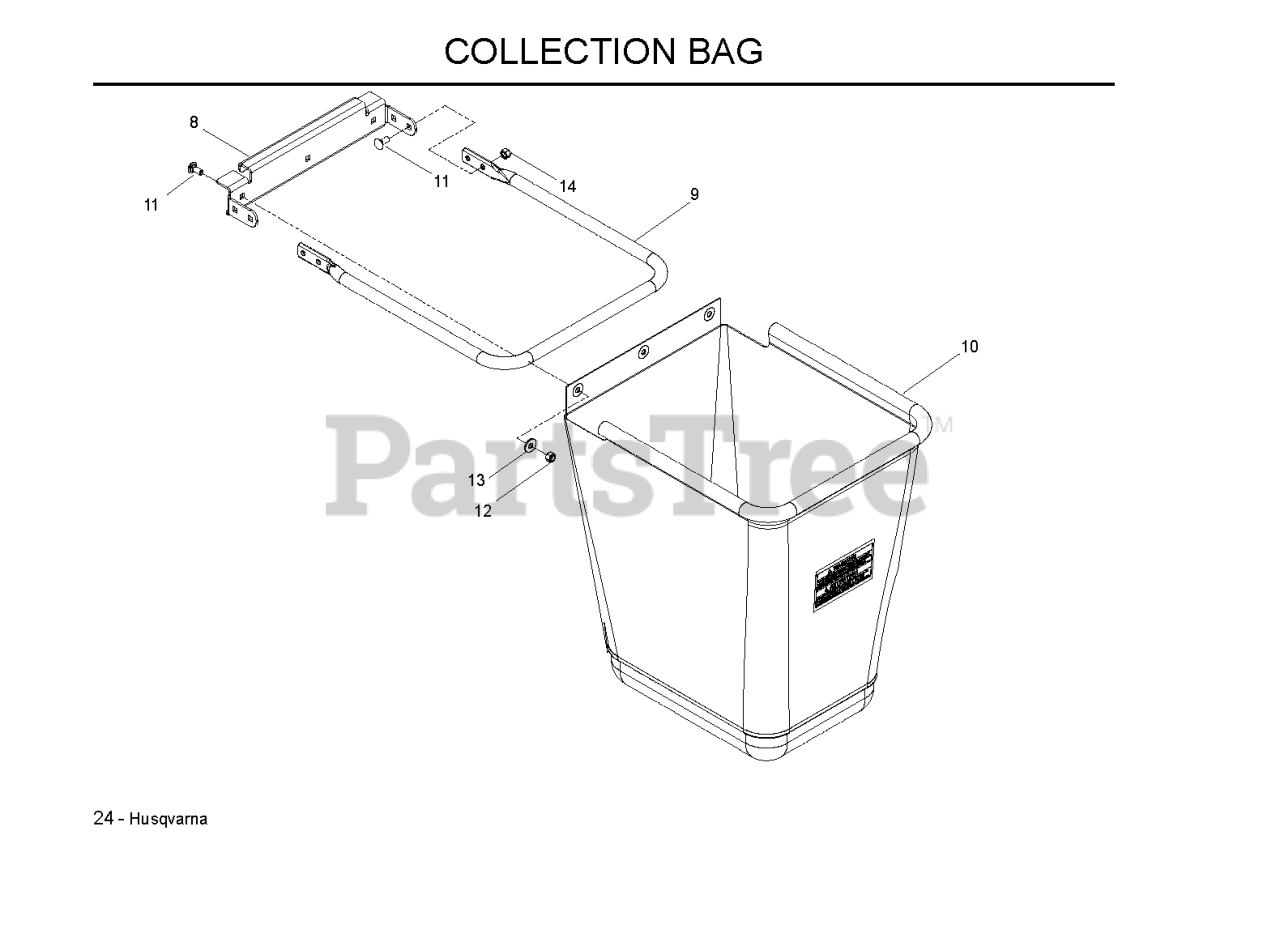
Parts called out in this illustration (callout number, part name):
8	HANGER, BAG
9	TUBE BAG FRAME
10	BAG, SMALL
11	BOLT 5/16C X 3/4" CARRIAGE
12	NUT 5/16 NYLOC
13	WASHER 5/16 FLAT
